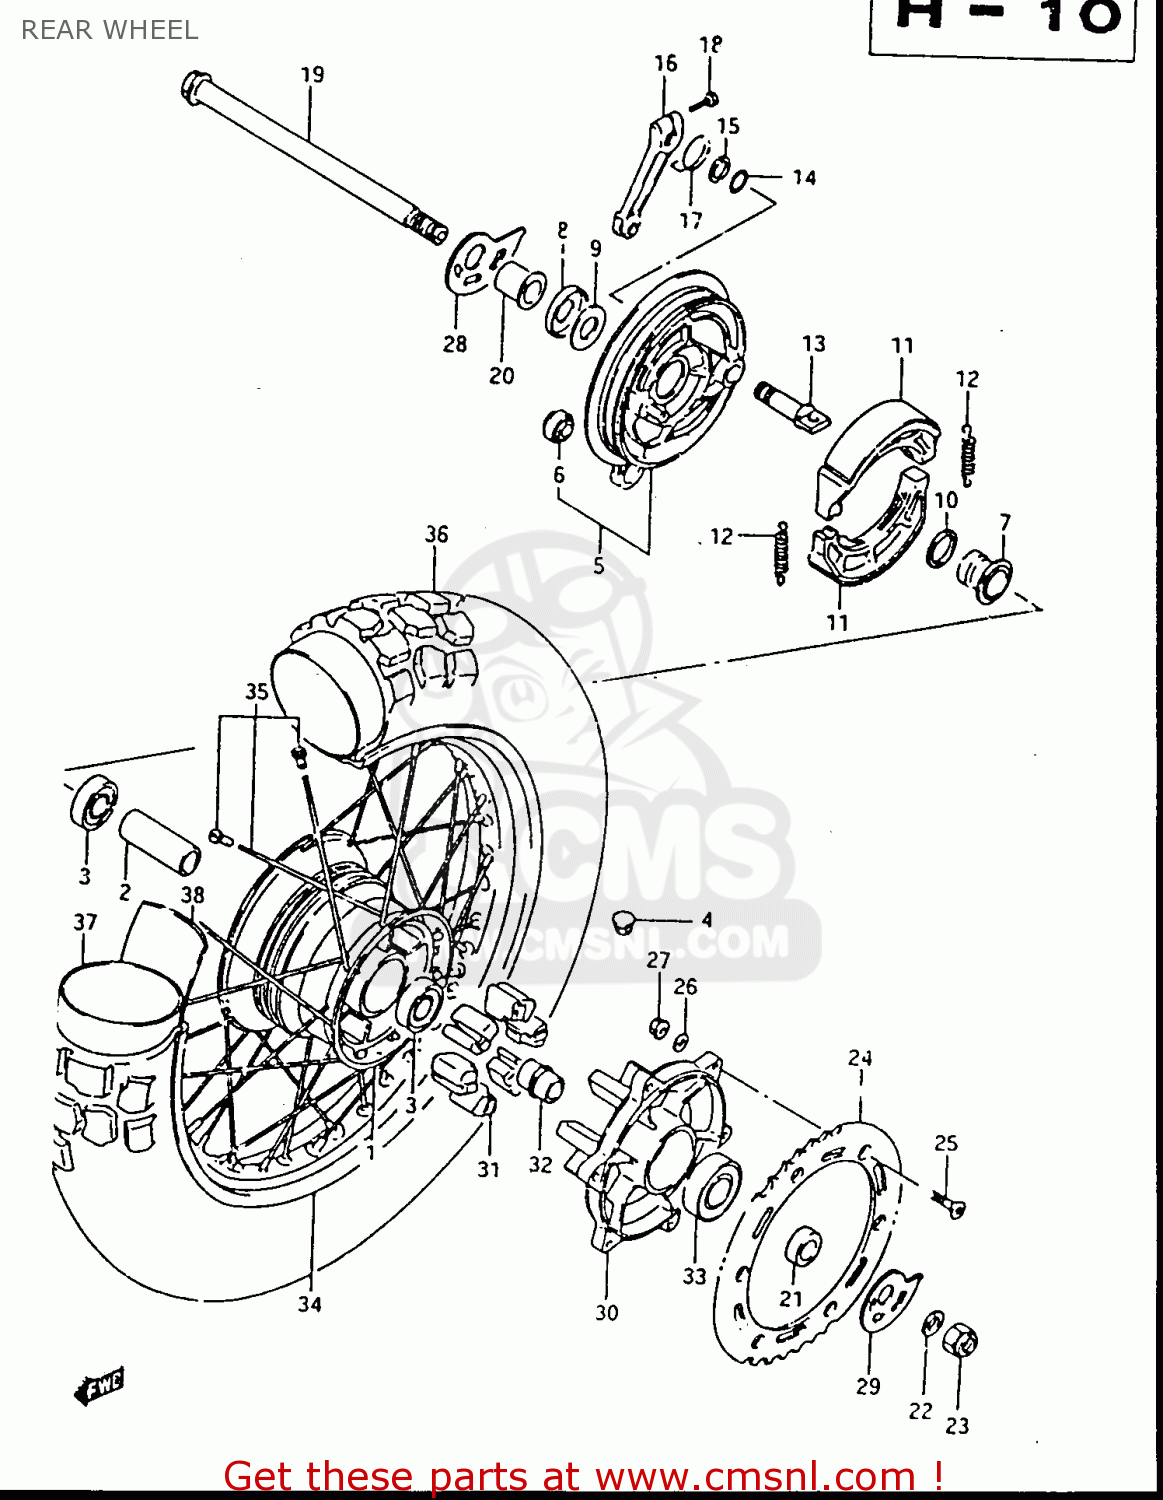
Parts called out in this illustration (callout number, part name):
1	DRUM,REAR HUB
2	SPACER (17.5X25X90)
3	BEARING
4	CAP(OD:12)
5	PANEL SET,REAR HUB
6	SPHERICAL BRNG,TORQUE LINK
7	SPACER,REAR BRAKE ANCHOR
8	CVR,RR BRAKE AHR PNL DUST SEAL
9	WASHER
10	SEAL,OIL(24X31X5)
11	SHOE,BRAKE
12	SPRING(L:34)
13	CAM,REAR BRAKE
14	O-RING (D:2.4 ID:13.8)
15	WASHER (14.5X22X1.6)
16	LEVER,RR BRAKE CAM
17	SPRING
18	BOLT
19	AXLE,RR
20	SPACER,REAR AXLE,RIGHT
21	SPACER (17X33X11)
22	WASHER
23	NUT
24	SPROCKET,REAR
25	BOLT(8X30.5)
26	WASHER
27	NUT
28	ADJUSTER,CHAIN RH
29	ADJUSTER,CHAIN LH
30	DRUM,RR SPROCKET MOUNTING
31	CUSHION,REAR DRUM
32	RETAINER,RR SPROCKET DRUM
33	BEARING(25X52X15)
34	RIM,REAR WHEEL
35	SPOKE SET,REAR WHEEL
36	TIRE
37	TUBE ASSEMBLY,WHEEL,INNER
38	PROTECTOR,INNER TUBE
